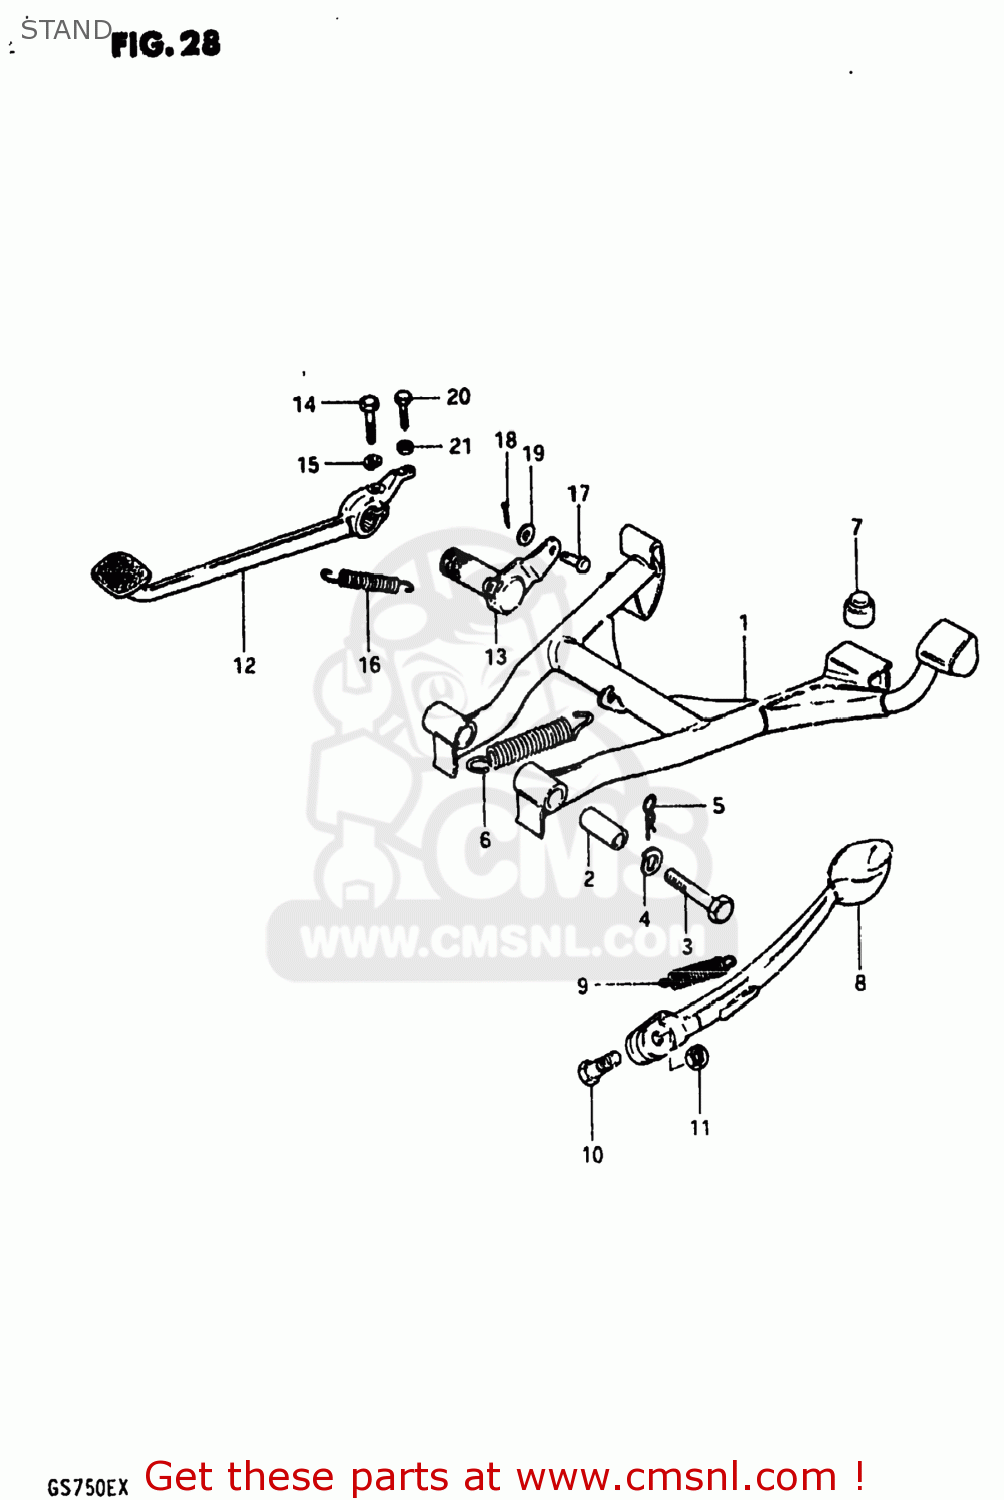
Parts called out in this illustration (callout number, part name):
1	STAND,CENTER
2	SPACER(10X16X38.8)
3	BOLT
4	LOCK WASHER
5	CLIP
6	SPRING
7	CUSHION
8	STAND,SIDE
9	SPRING
10	BOLT(10X30)
11	NUT
12	PEDAL,BRAKE
13	ARM,BRAKE PEDAL ROD
14	BOLT
15	LOCK WASHER
16	SPRING
17	PIN
18	PIN
19	WASHER
20	BOLT
21	NUT
